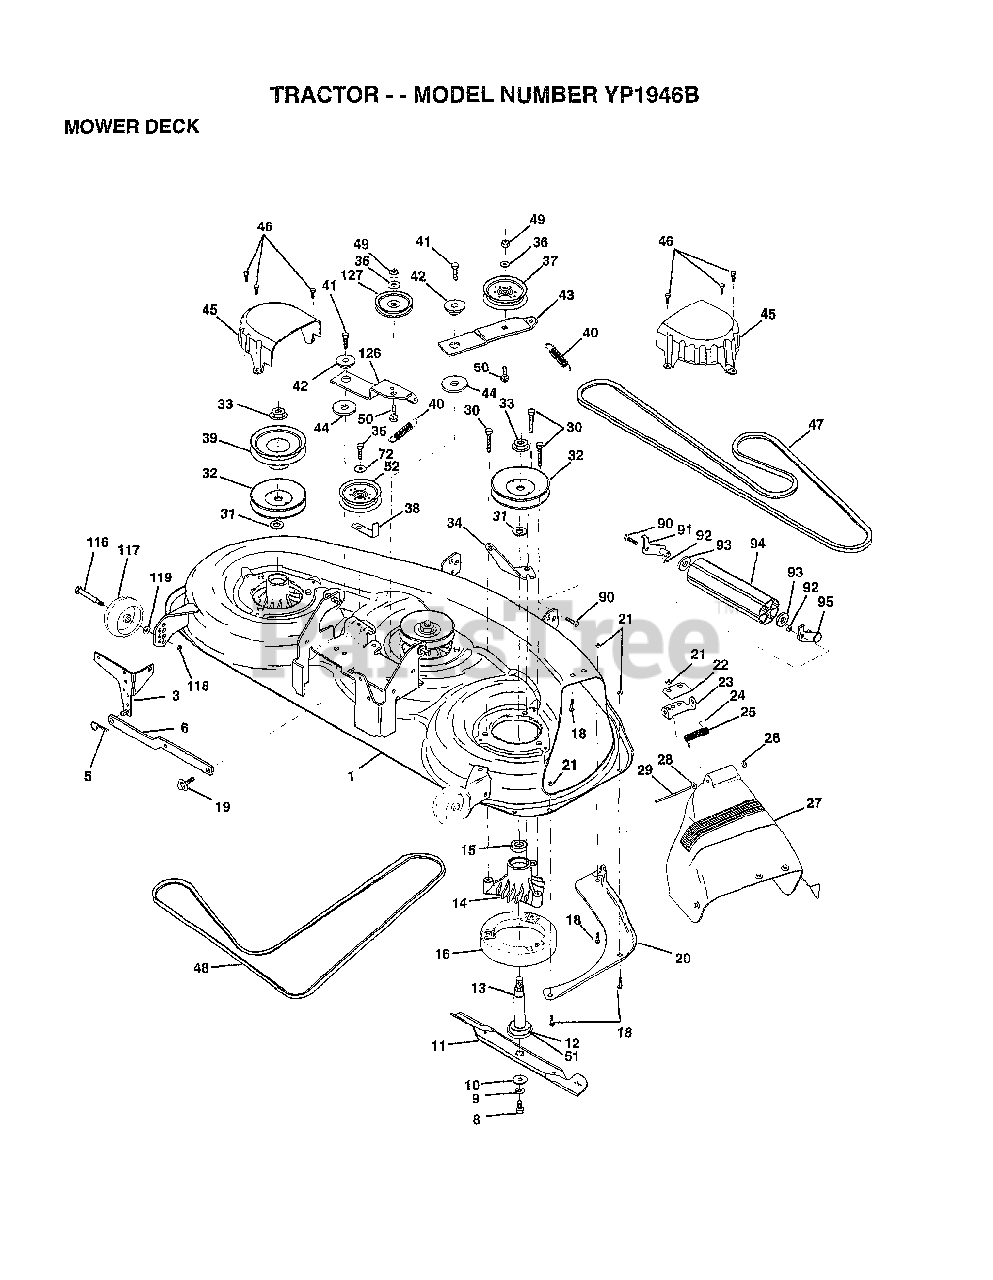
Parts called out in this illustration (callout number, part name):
1	"MOWER ASM 46"""
3	BRKT.ASM.SW.44/50
8	BLADE BOLT
10	WASHER.HARD.BLADE
11	"BLADE.HIGHLIFT46"""
12	BEARING.BALL
13	SHAFT.ASM.W/BRNG
14	HOUSING.MAND.44.V
15	BEARING
16	STRIPPER RND MWR
18	BOLT
19	BOLT SHD 5/16-18
20	BAFFFLE.VORTEX.46
22	STIFFENER BRKT
23	DEFLECTOR BRKT
27	SHIELD DEFLECTOR
28	WASHER
29	HINGE ROD
30	"SCREW-THD ROLL,WA"
31	WASHER
32	PULLEY.MAND.36/46
34	ANCHOR.SPRING.46
35	SCREW LT
36	WASHER
37	FLAT IDLER PULLEY
38	"KEEPER BELT,IDLER"
39	PULLEY.DRV.DCK.46
40	"SPRING.SEC.44""VEN"
41	SCREW
42	SPACER RETAINER
43	ARM.IDLER.DECK.46
44	HARDENED WASHER
45	COVER.MANDREL.46
46	SCREW.1/4-20X5/8
47	BELT-V.SEC.46.KEL
48	BELT V PRIM 50
50	BOLT.3/8-16X1.50
51	WASHER.FELT.
52	"PULLEY IDLER,FLAT"
72	WASHER HYT
90	BOLT
92	NUT
93	WASHER
116	BOLT.SHOULDER
117	WHEEL GAGE DONUT
118	LOCKNUT
119	WASHER
126	ARM.IDLER.PRIM.46
127	PULLEY.IDLER.4.25
